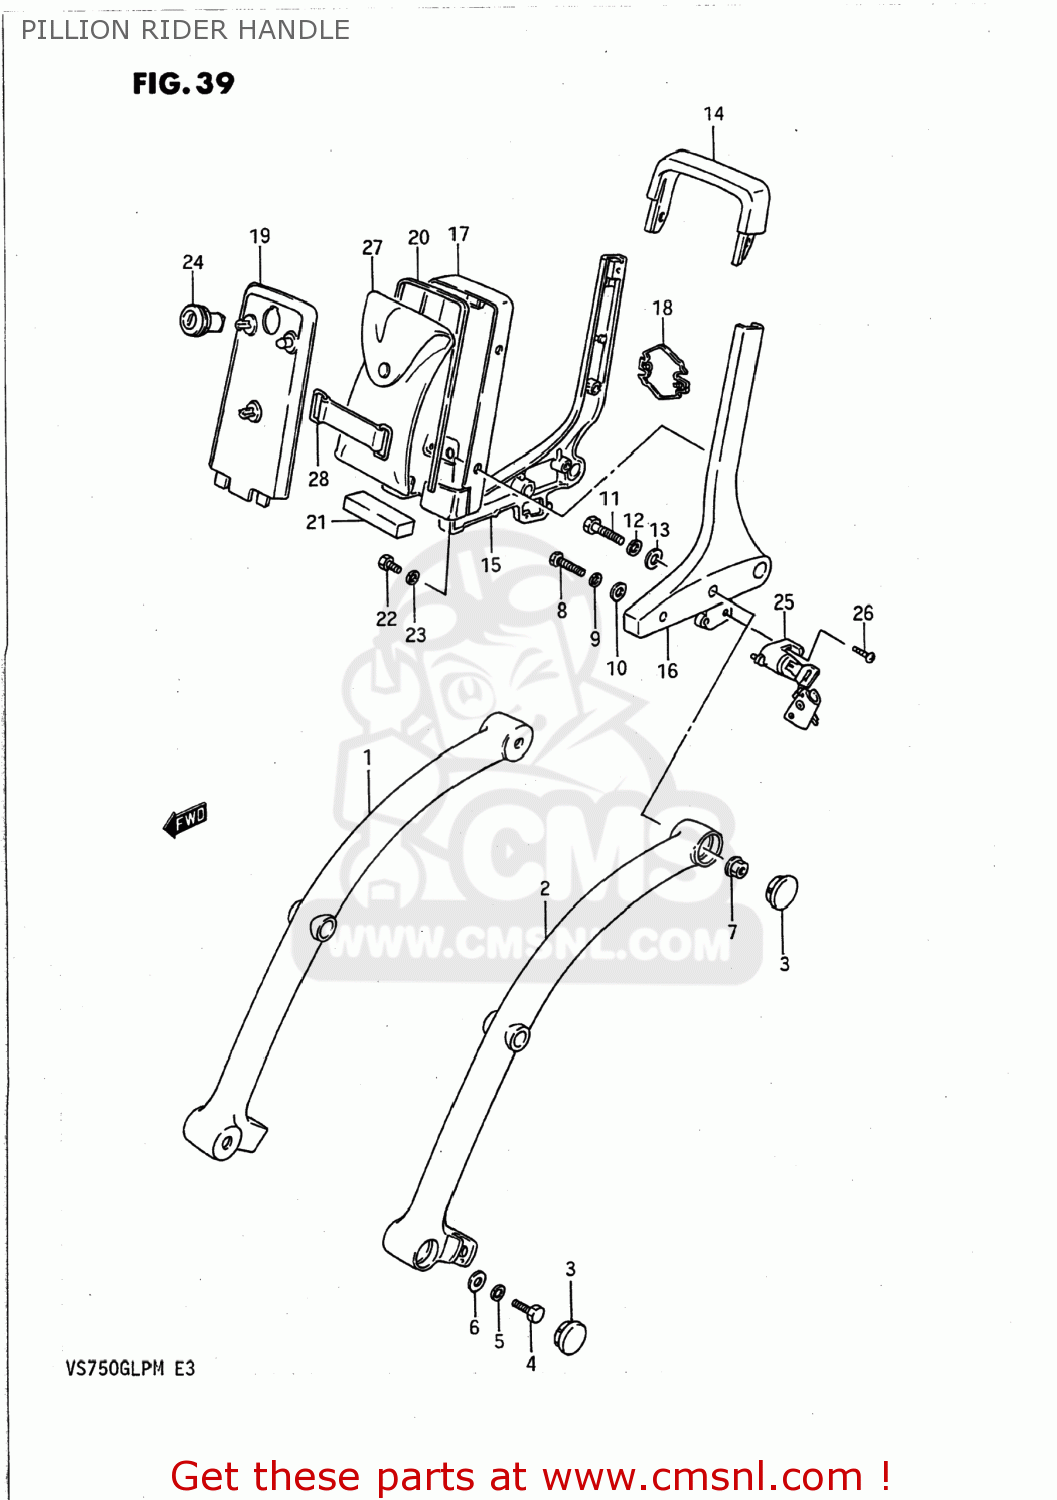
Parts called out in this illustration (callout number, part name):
1	GRIP,FRAME HANDLE,RIGHT
2	GRIP,FRAME HANDLE,LEFT
3	CAP,FRAME HANDLE GRIP
4	BOLT
5	LOCK WASHER
6	WASHER
7	NUT, WHEEL SET
8	BOLT ,6X35
9	WASHER,LOCK
10	WASHER, LOWER
11	BOLT,FRONT
12	WASHER,LOCK,8.
13	WASHER
14	HANDLE,PILLION RIDER
15	HANDLE,PILLION RIDER
16	HANDLE,PILLION RIDER
17	HOLDER,TOOL
18	EMBLEM
19	HOLDER,TOOL FR
20	MOLDING,TOOL HOLDER RR
21	CUSHION,TOOL BACK
22	BOLT
23	WASHER,LOCK
24	LOCK SET,TOOL HOLDER
25	LOCK SET,HELMET
26	SCREW
27	TOOL ASSY
28	BAND
29	CARRIER ASSEMBLY,REAR
